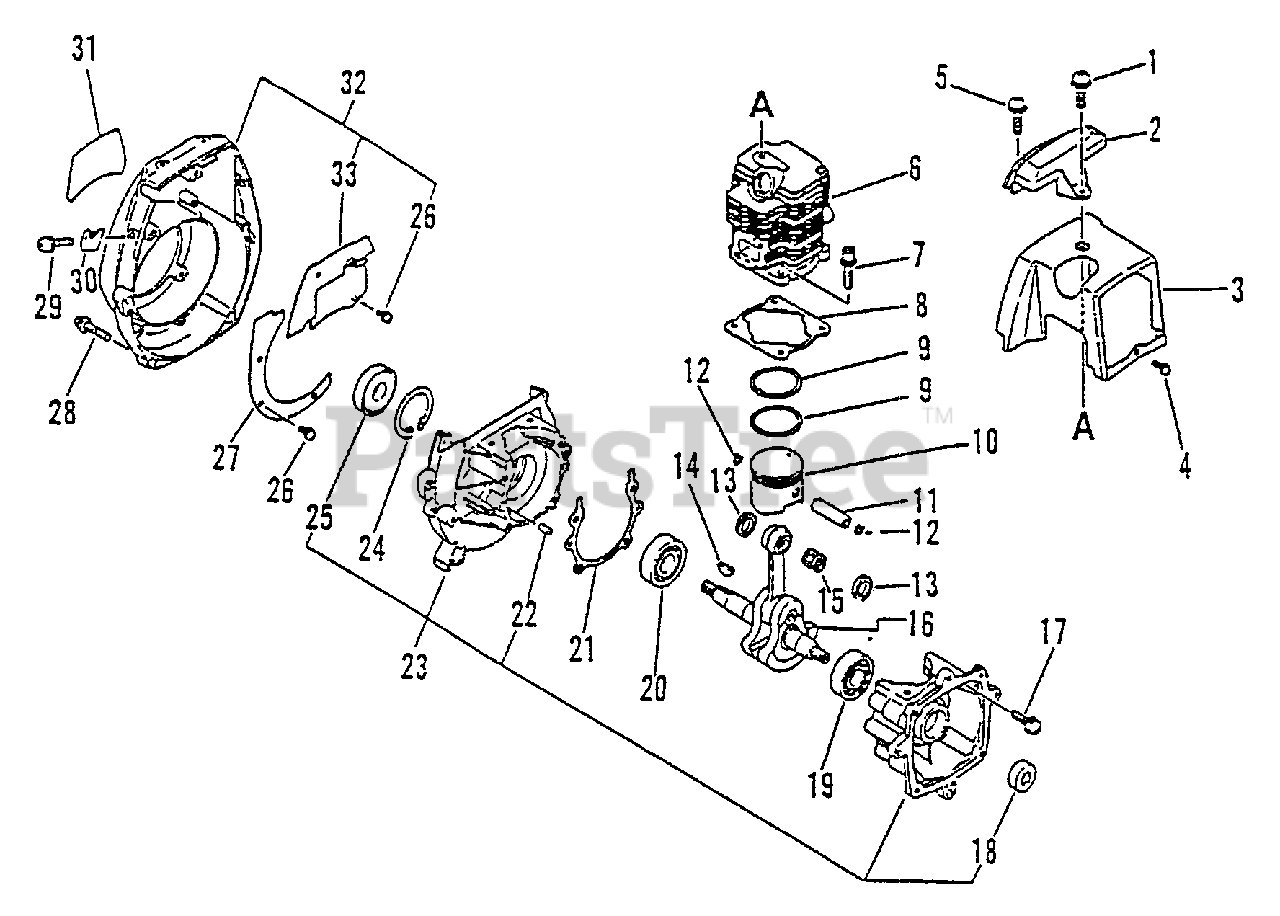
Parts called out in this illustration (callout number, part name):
1	SCREW 5×16
2	GUARD, TOP
3	COVER, ENGINE
4	SCREW 4×10
5	SCREW 4×14
6	CYLINDER
7	BOLT 5×20
8	GASKET, CYLINDER
9	RING, PISTON
10	PISTON KIT
11	PIN, PISTON
12	RING, SNAP
13	WASHER, THRUST
15	BEARING, NEEDLE
16	CRANKSHAFT
17	SCREW 5×25
18	SEAL, OIL 12
19	BEARING, BALL 6001
20	BEARING, BALL - 6201 C3
21	GASKET, CRANKCASE
22	PIN, LOCATING 4
23	CRANKCASE KIT
24	RING, SNAP Ø32
25	SEAL, OIL 12
26	SCREW 4×8
27	PLATE, GUIDE
28	SCREW 5×20
29	SCREW 4×10
30	HOLDER, CABLE
31	LABEL, MODEL
32	FAN CASE ASSY
33	PLATE, GUIDE
